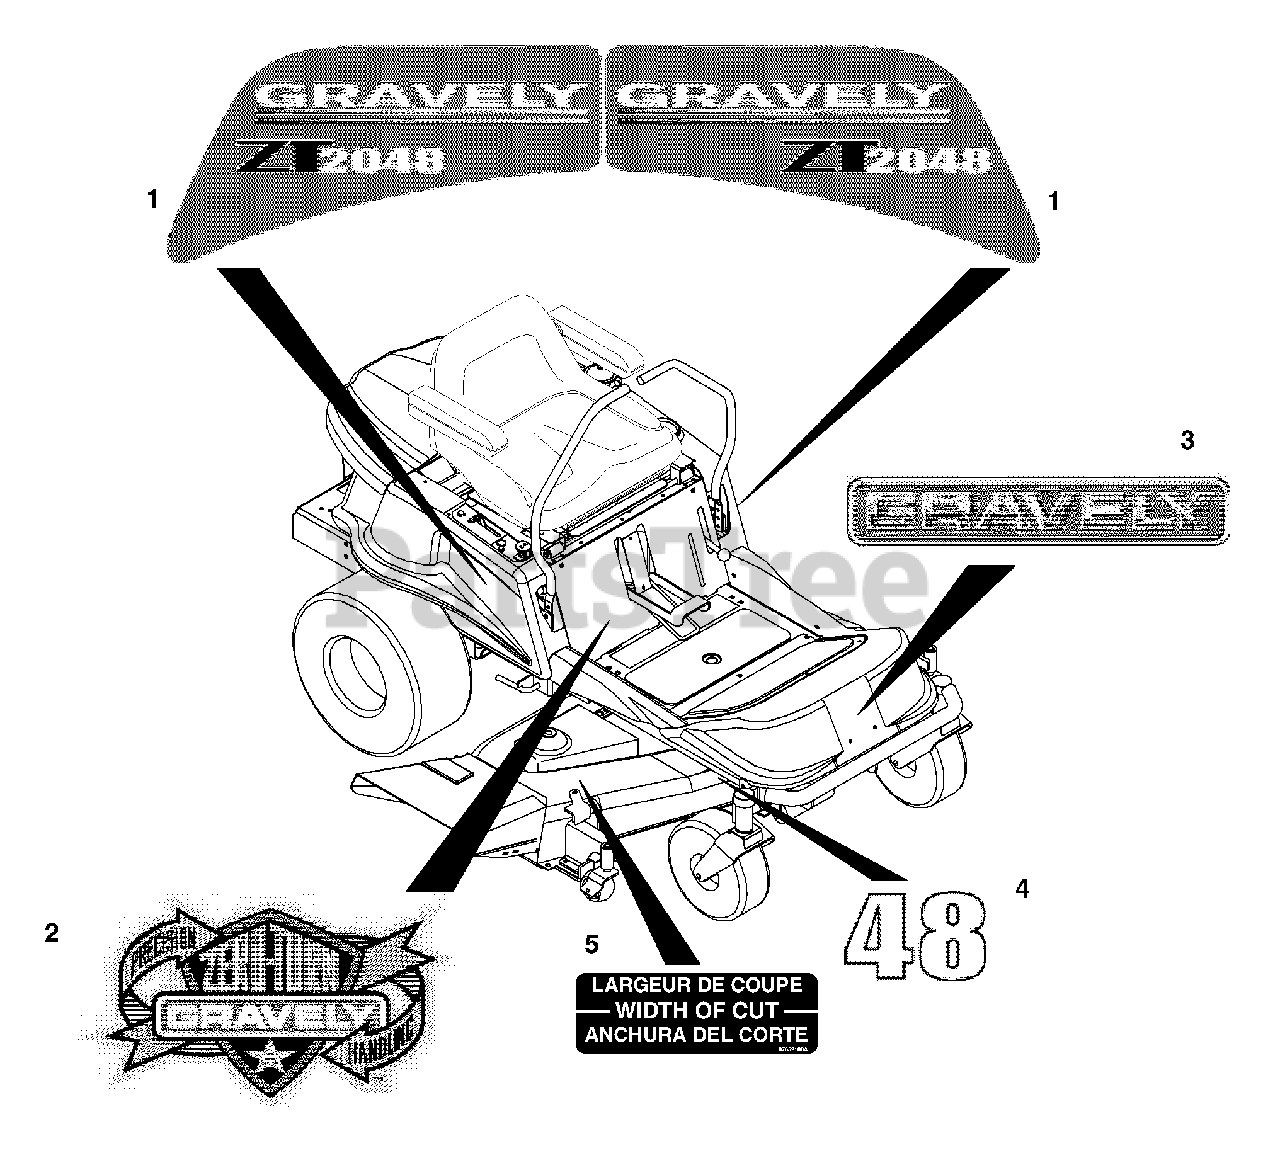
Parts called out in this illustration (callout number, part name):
1	Decal, Set ZT 2048
1	Decal, Set ZT 1842
2	Decal, Zero Turn
3	Decal, Gravely Logo
4	Decal, 48
4	Decal, 42
5	Decal, Width of Cut
